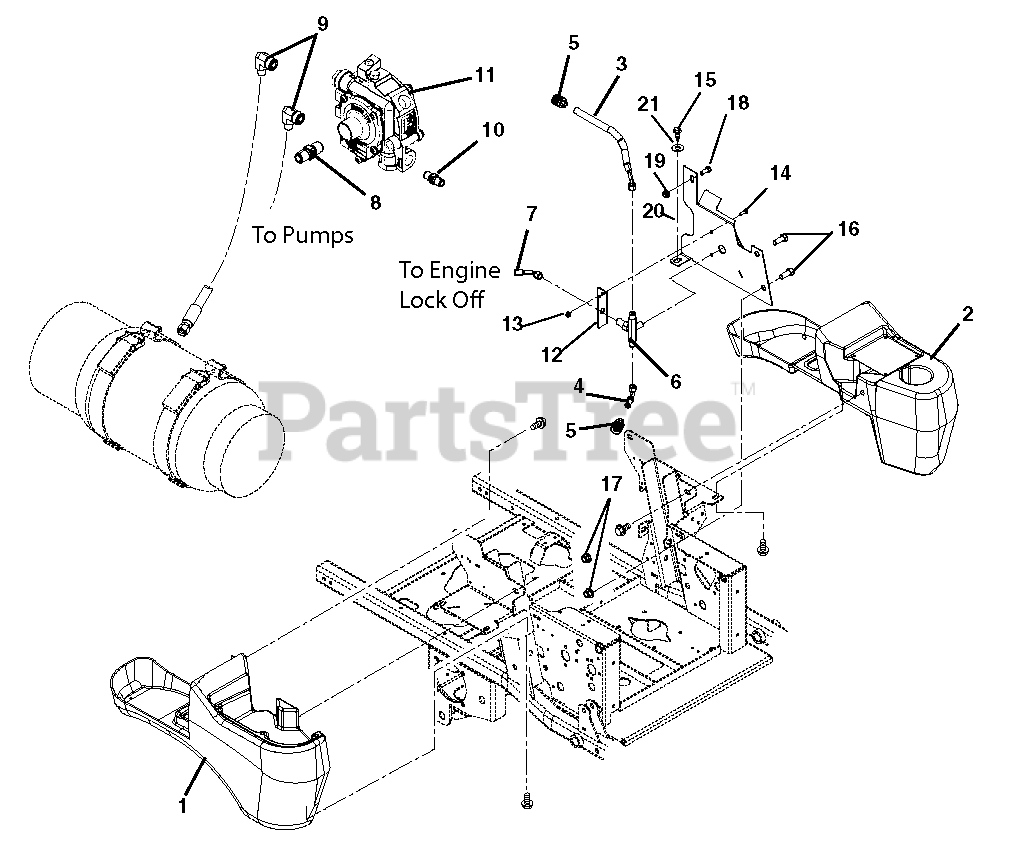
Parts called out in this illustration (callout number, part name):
1	Fender, RH 200 Series LPG
2	Fender, LH 200 Series LPG
3	Hose,LPG
4	Hose,LPG
5	Fitting, LPG Tank
6	Valve, Sherwood T
7	Hose, LPG
8	Fitting, Barb .50-.38
9	Fitting, barb 1/4NPT x 8ORF 90 Degree
10	Fitting, LPG STRAIGHT 1/4NPT PARKER 216P-4
11	Regulator, LPG IMPCO T60
12	Mount, Fuel T
13	Nut, Locking-Top-Flange .31-18
14	Bolt, Hex .31-18 x .75 Grade 5
15	Weldment, Support Fuel T
16	Bolt, Hex .50-13 x1.25 Grade 5
17	Nut, Locking-Top-Flange .50-13
18	Bolt, Hex .38-16 x 1.50 Grade 5
19	Nut, .38-16 Nyloc Flange
20	Screw, Tapping .38-16 x 1.00 Hex Washer Head
21	Washer, Flat-Steel .438 x 1.00 x .083
